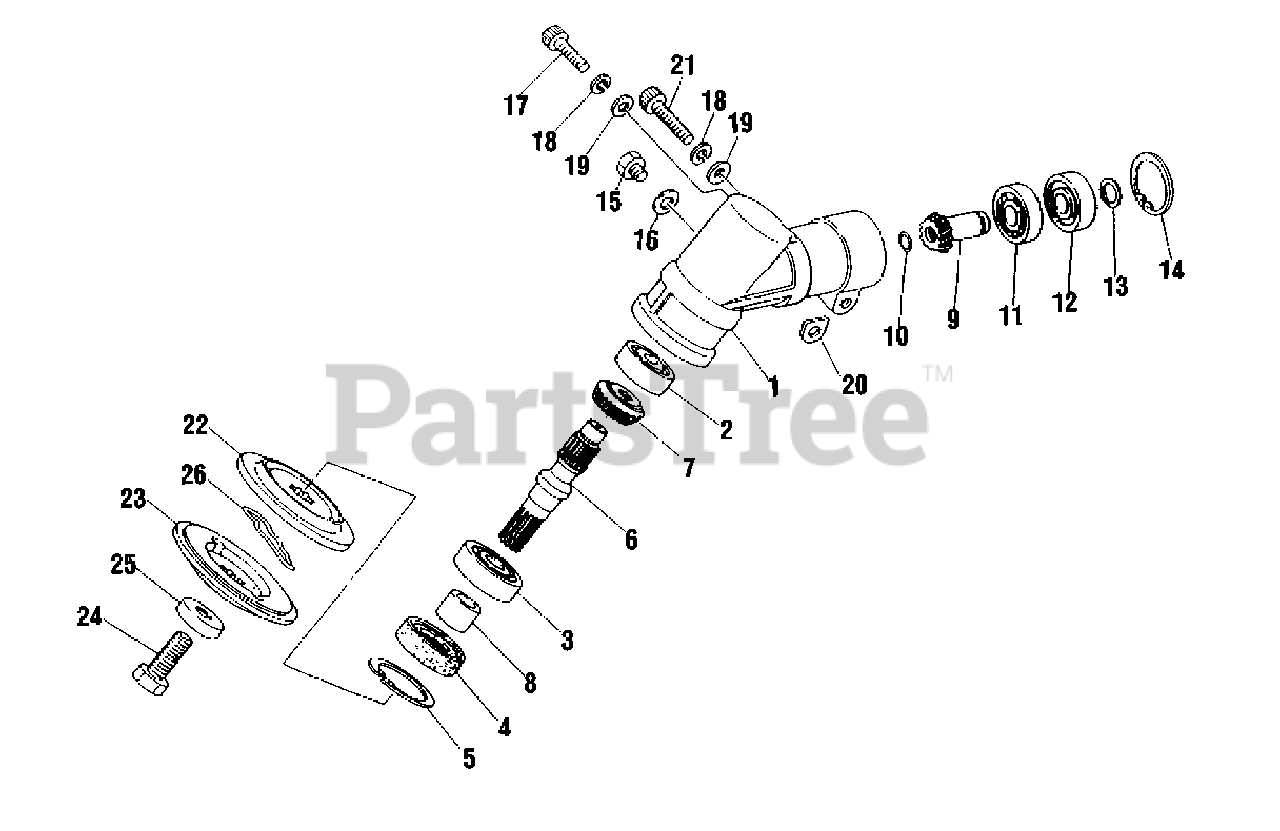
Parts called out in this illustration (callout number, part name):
1	CASE, GEAR
2	BEARING, BALL 6000DDU
3	BEARING, BALL 6202
4	SEAL, OIL
5	RING, SNAP Ø35
6	SHAFT, GEAR
7	GEAR, BEVEL
8	COLLAR
10	RING, RETAINING
11	BEARING, BALL 6001
12	BEARING, BALL 6001ZZ
13	RING, SNAP Ø12
14	RING, SNAP Ø28
15	BOLT M6×10
16	WASHER
17	BOLT
18	WASHER, SPRING 6
19	WASHER 6.5×11.5×0.8
20	D-WASHER
21	BOLT
22	HOLDER (A)
23	HOLDER (B)
24	BOLT 10×30
25	GUARD, BOLT
26	PIN, SLIDE
